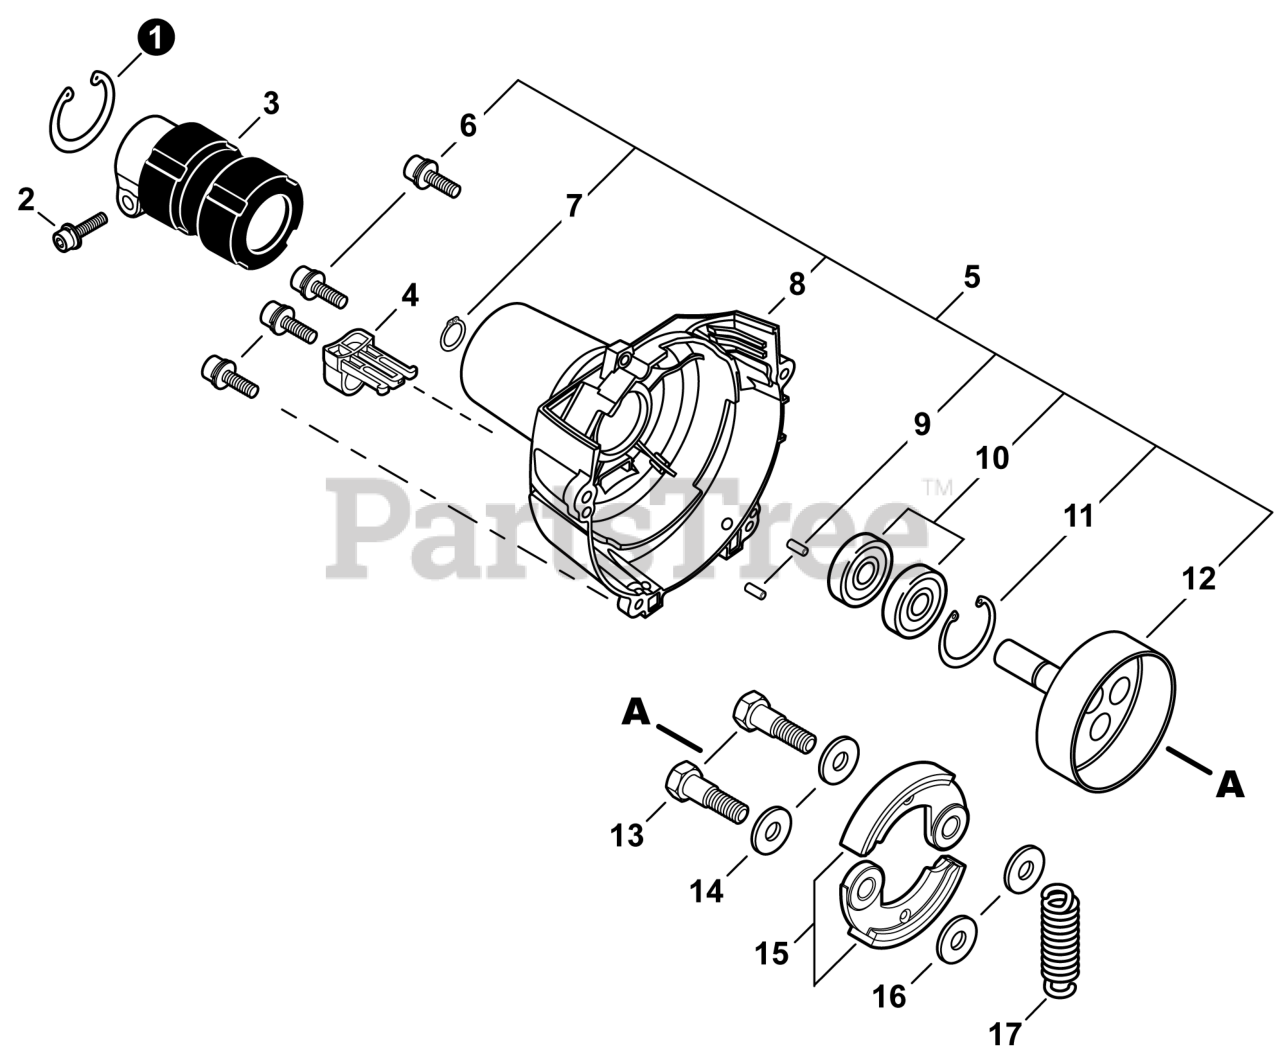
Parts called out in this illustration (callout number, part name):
1	RING, SNAP 42
2	BOLT 5x28
3	HOLDER, MAIN PIPE
5	COVER ASSY, FAN
6	BOLT 4x16
7	RING, SNAP 12
8	COVER, FAN
9	PIN, LOCATING 4
10	BEARING, BALL 6001
11	RING, SNAP 28
12	DRUM, CLUTCH
13	BOLT, CLUTCH 8x7.9xM6
14	WASHER, SPRING 8.5x16x0.5
15	SHOE, CLUTCH
16	WASHER 6.2x19x1.0
17	SPRING, CLUTCH
